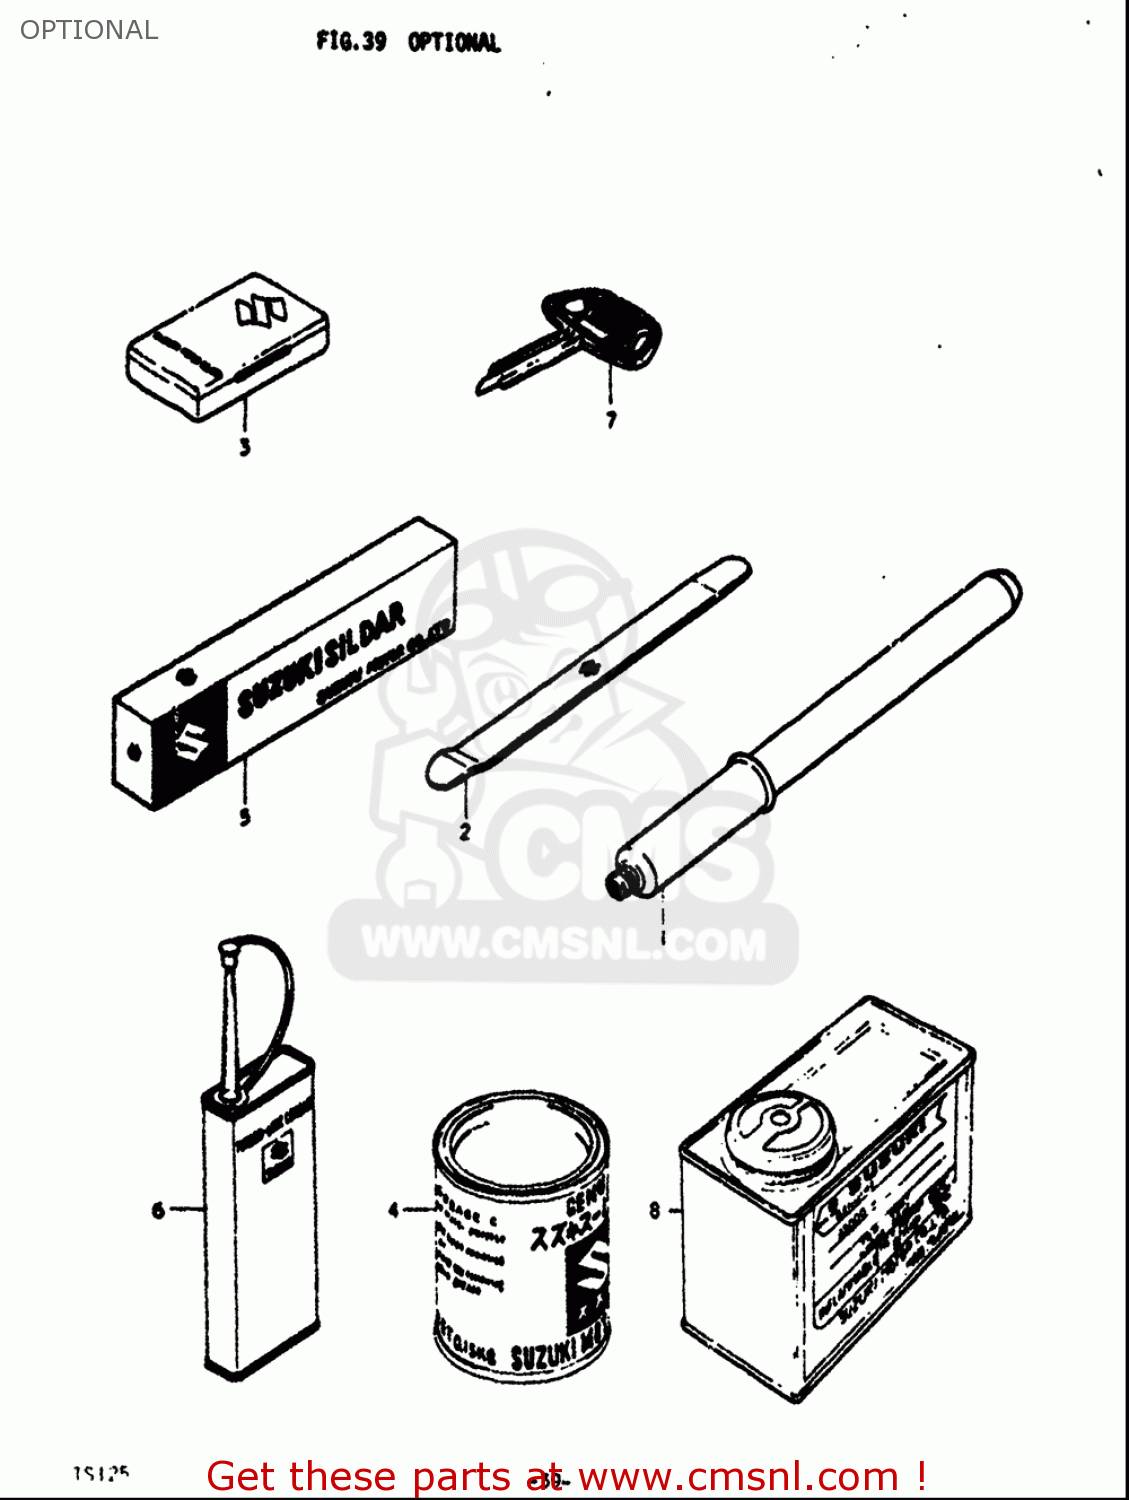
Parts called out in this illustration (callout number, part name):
2	LEVER,TIRE
4	GREASE(C)EP2 LITHIUM 150G
6	THREAD LOCK NO.1401 CLEAR 200G
